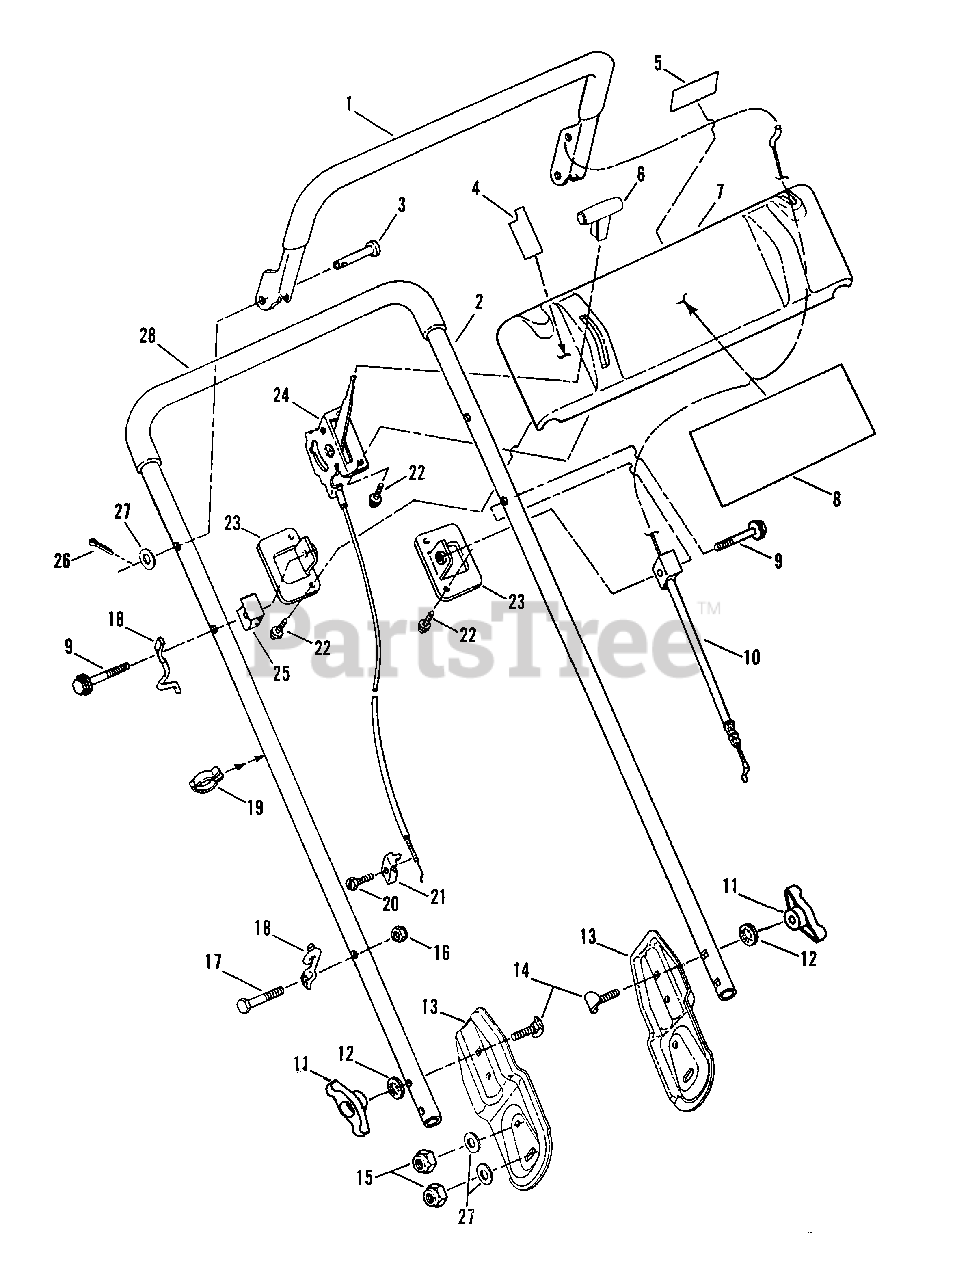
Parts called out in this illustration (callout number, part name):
1	CONTROL, Blade
2	HANDLE, Upper
3	PIN, 5/16 x 1-7/16" Clevis
4	DECAL, Engine Speed (W/O Choke)
5	DECAL, OPC Instruction
6	KNOB, Throttle Control
7	CONSOLE, Control
8	DECAL - SNAPPER (Platinum Series)
9	SCREW, 1/4-20 x 2" Hex Washer Head, Self-Tapping
10	ASSEMBLY, Cable, Blade Control (L21550 & NL21550)
11	KNOB, 5/16-18
12	WASHER, 5/16 Internal Tooth Lock
13	BRACKET, Handle
14	SCREW, 5/16-18 x 2" Curved Head
15	NUT, 5/16-18 Hex Nyloc
16	NUT, 1/4-20 Hex Nyloc
17	SCREW, 1/4-20 x 1 1/2" Hex Head Cap, Grade 5
18	GUIDE, Rope
19	CLAMP, Cable
20	SCREW, #10-32 x 5/8" Slotted Hex Head, Self-Tapping
21	CLAMP, Cable
22	SCREW, #10-16 x 1/2" Hex Washer Head, Self-Tapping
23	BRACKET, Console
24	CONTROL, Engine Speed (Briggs & Stratton Engine W/O Choke)
25	FITTING, Handle Bar
26	COTTER-PIN, 3/32" x 1/2"
27	WASHER, Flat, .34 I.D. x .69 O.D.
28	GRIP, Foam
